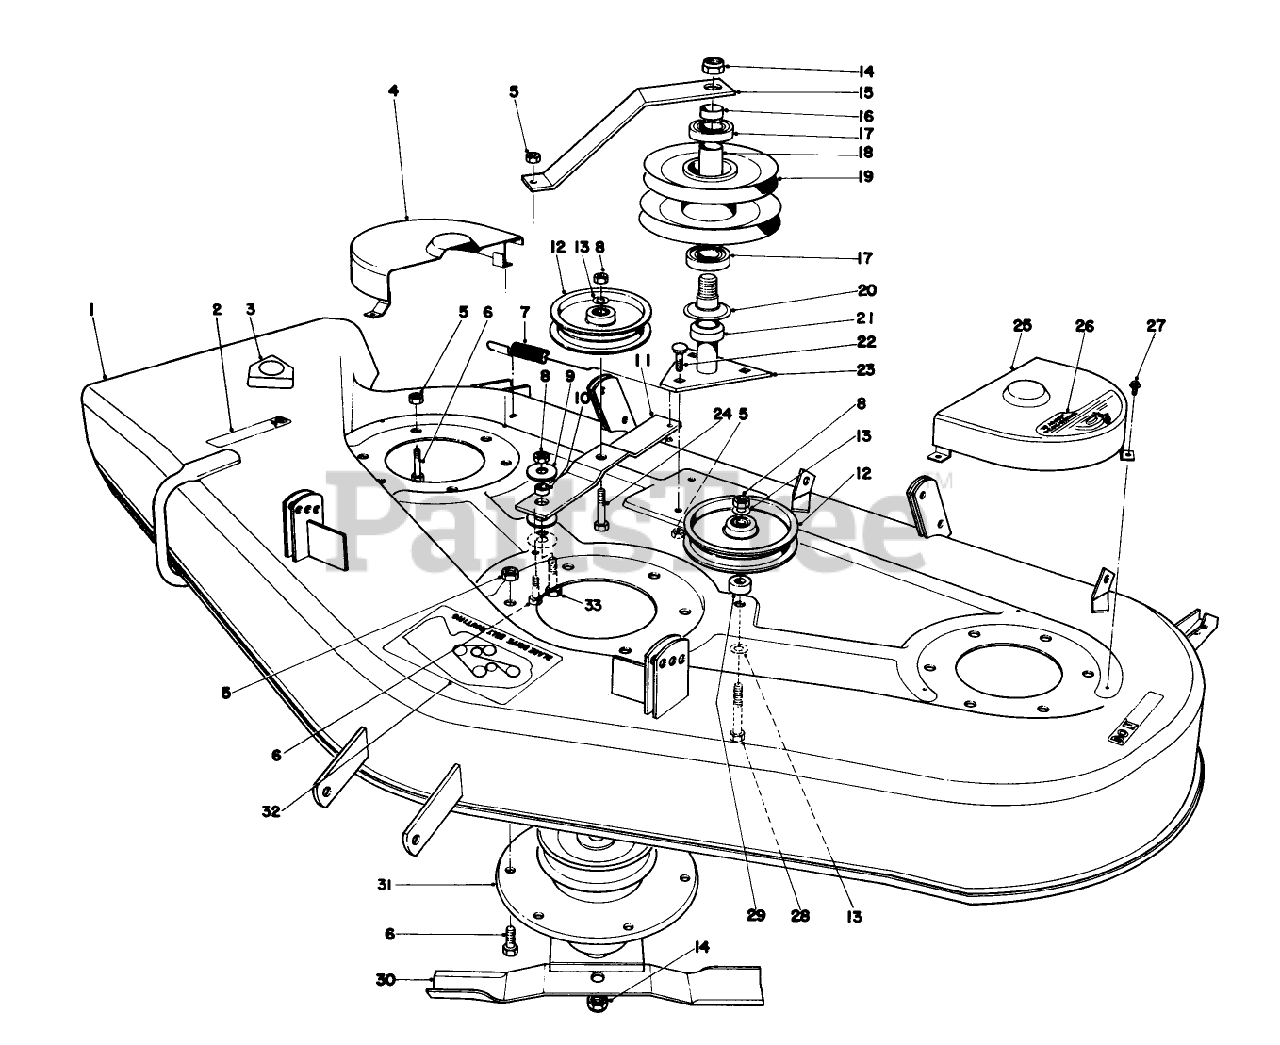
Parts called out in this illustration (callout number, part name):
3	DECAL-DANGER
5	NUT-LOCK, CONE
6	SCREW-HH
8	NUT-LOCK, CONE
9	WASHER
10	IDLER BRKT SPACER
12	PULLEY-IDLER
13	WASHER-FLAT
14	NUT-LOCK, NI
17	BEARING-BALL
20	DUST COVER
22	BOLT-CARR
23	SHAFT SADDLE ASM
24	SCREW-HH
27	SCREW-HWHTF
28	SCREW-HH
29	SPACER *O
31	Spindle ASM
33	SCREW-HH
